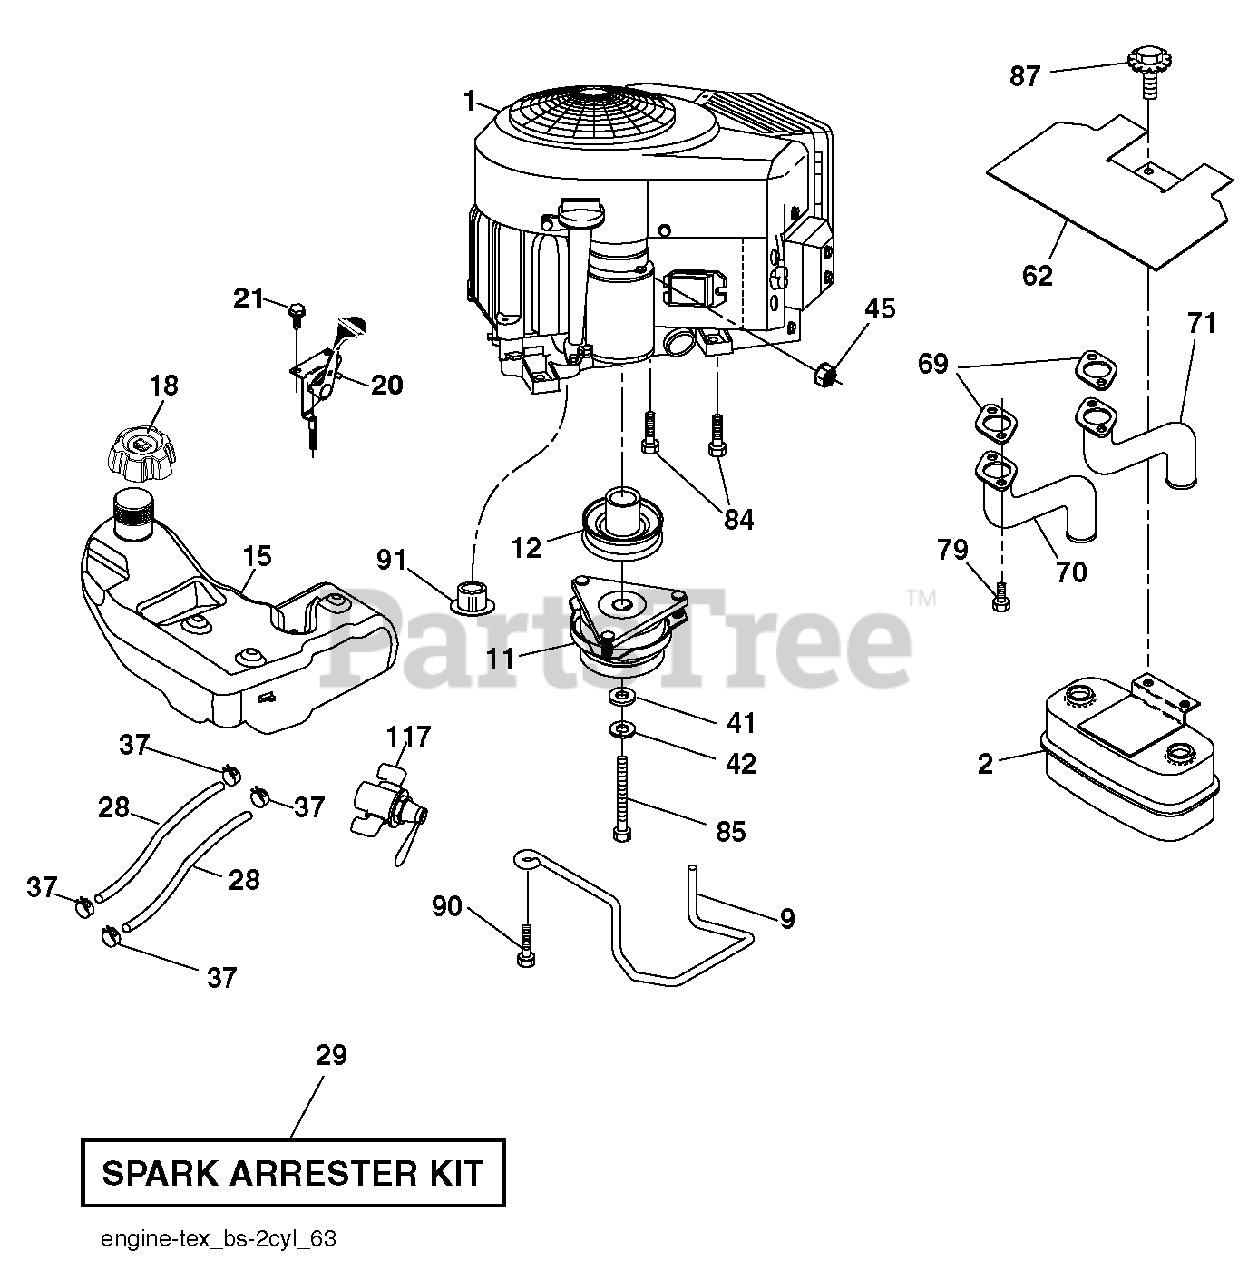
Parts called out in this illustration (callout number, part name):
1	Husqvarna TBD
2	MUFFLER.TWIN.CYL.LOW.TONE
9	KEEPER.BELT.ENGINE.4.2
11	CLUTCH.ELECTRIC.LT.48"*
12	PULLEY.ENGINE.TUFFTORQ
18	CAP.FL.R.3'N/CARB.H.CROWN.498
20	CONTROL.TH/CK.COBRA.B&S.TWN.
21	SCREW.#10 X 0.750.BOS
28	REPL BY 532 00 85-43
29	KIT.SPARK ARRESTOR 794945 B&S
37	HOSE CLAMP
42	LOCKWASHER
45	NUT
62	SHIELD.HEAT.MUFFLER
69	GASKET.MUFFLER
70	RP.EXHAUST.TUBE.LH.BS/TWIN
71	EXHAUST.TUBE.RH.BS/TWIN
79	SCREW.SOCKET.HEAD.5/16-18
84	SCREW.3/8-16
85	BOLT HEX 7/16-20X4-1/4"
87	Bolt, 5/16-18 X 1-3/4
90	SCREW 3/8-16X1
91	BUSHING.1.375OD
117	VALVE FUEL RESERVE
